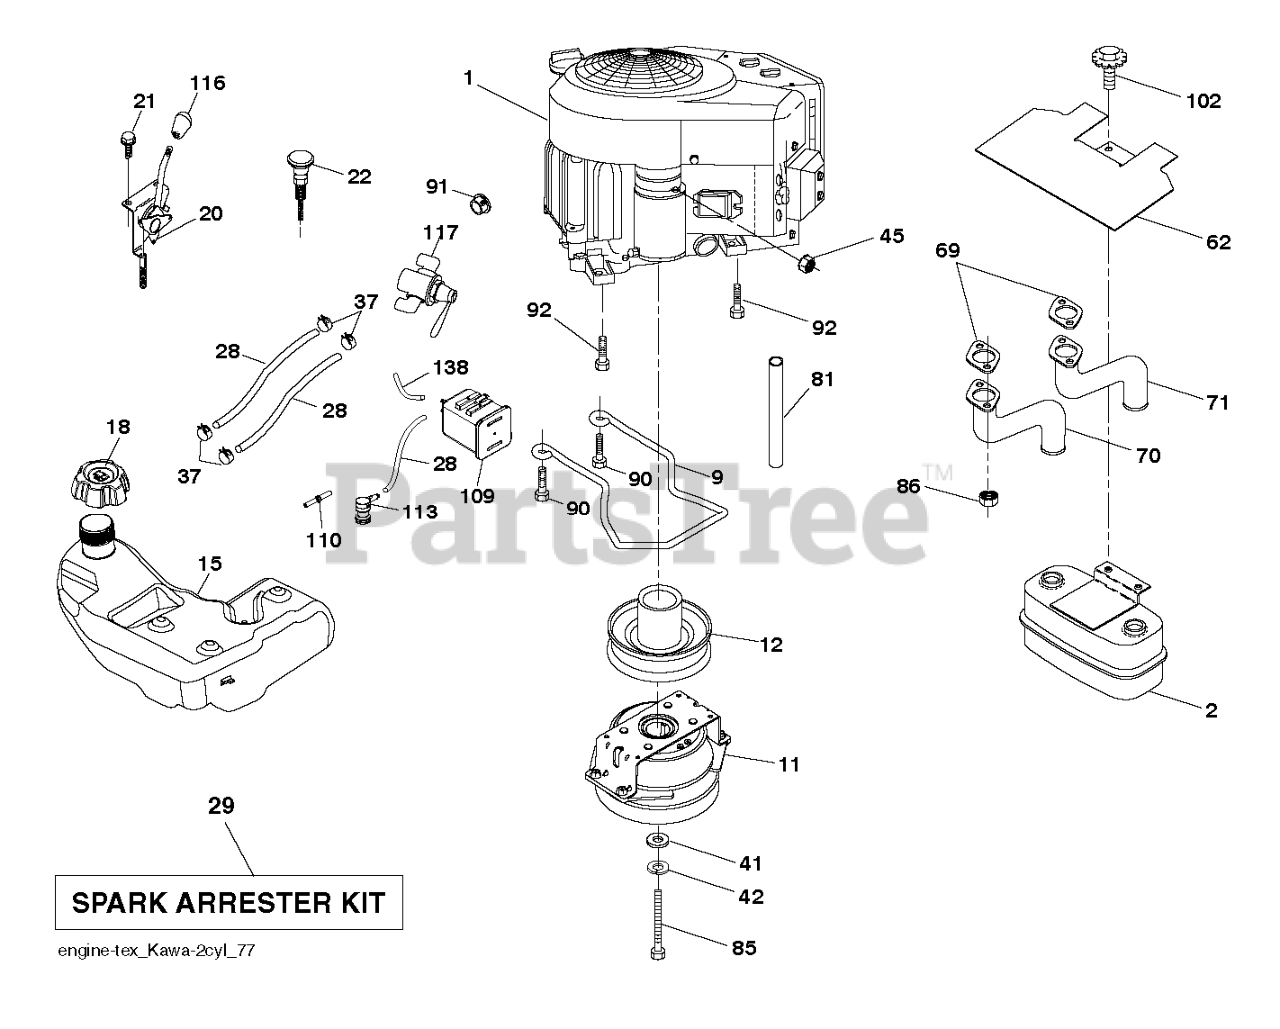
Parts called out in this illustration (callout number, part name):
2	MUFFLER.ASM.TWIN.MNTG.BRACKET
9	KEEPER.BELT.ENG.4.25"2.BLT.431
11	CLUTCH.OGURA.5.0PD.GT1.5A-EH01
12	PULLEY ENGINE
15	FUEL TANKS
20	CONTROL.THROTTLE.PRO.
22	CONTROL, CHOKE
28	LINE.FUEL.64"REAR.EMIS
29	KIT.SPARK ARRESTOR 794945 B&S
37	HOSE CLAMP
62	SHIELD.HEAT.MUFFLER
70	TUBE.EXHAUST.LH.FR961/FR730
71	TUBE.EXHAUST.RH.FR961/FR730
81	TUBE, DRAIN OIL ASM.
85	BOLT.HEX.7/16-20X3.GR5.YELLOW
86	NUT.HEX.FLANGE.TOPLOCK
90	SCREW 3/8-16X1
91	BUSHING.1.375OD
92	SCREW 3/8-16X1
102	SCREW
109	CANNISTER, CARBON
110	VALVE.ASM.ANTI-SLOSH
113	VALVE.SLANT.CARTRDG.90 DEG.TEX
116	KNOB - SHIFT
117	VALVE FUEL RESERVE
138	PURGE.LINE.36"REAR.CALIFORNIA
